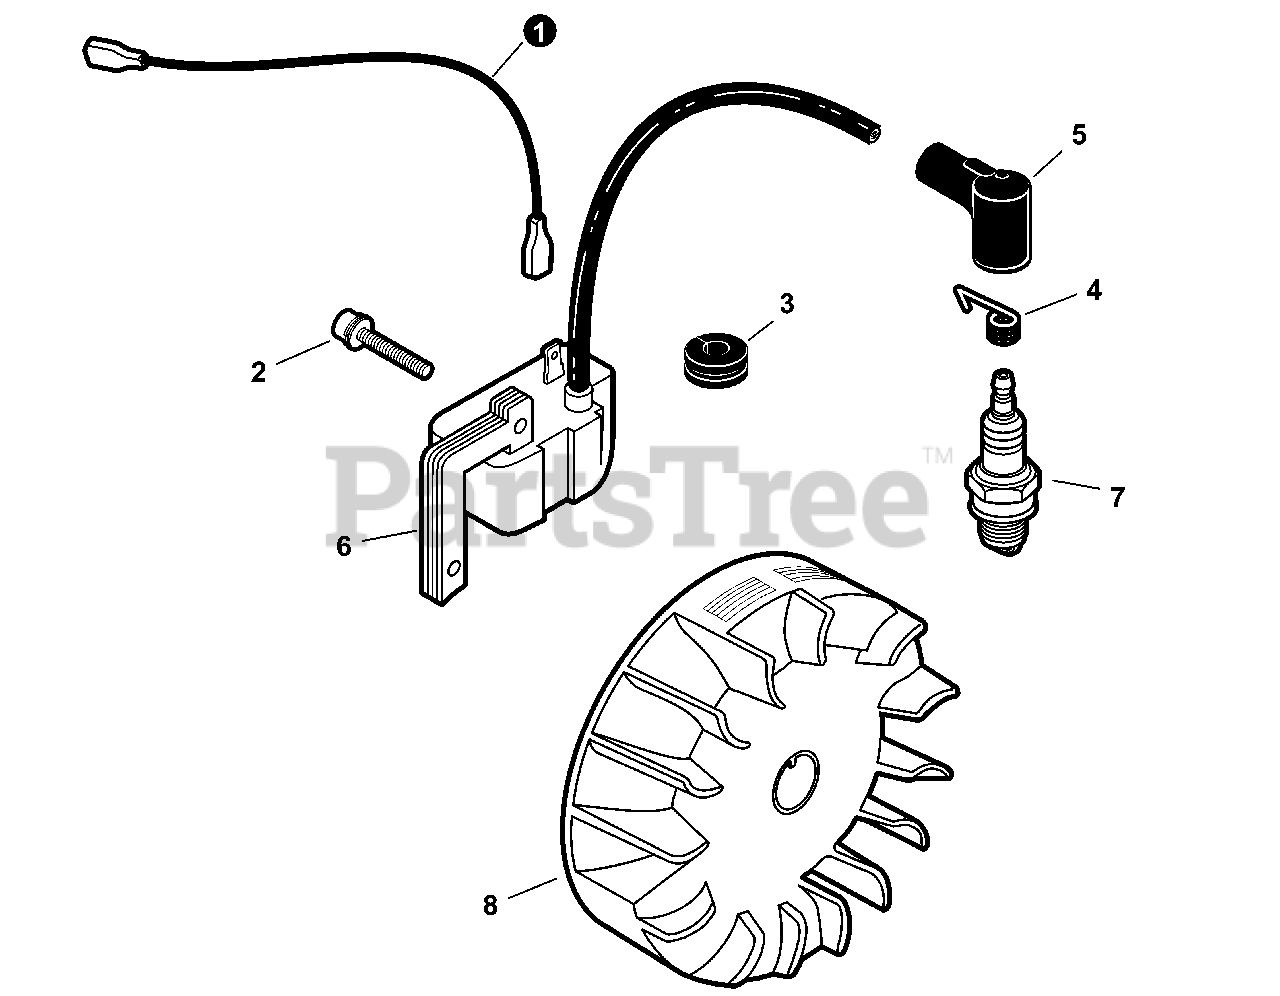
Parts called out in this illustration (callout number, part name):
1	LEAD
2	SCREW 4×22
3	GROMMET
4	TERMINAL, SPARK PLUG
5	CAP, SPARK PLUG
6	COIL, IGNITION
7	SPARK PLUG - BPM7A
8	FLYWHEEL
